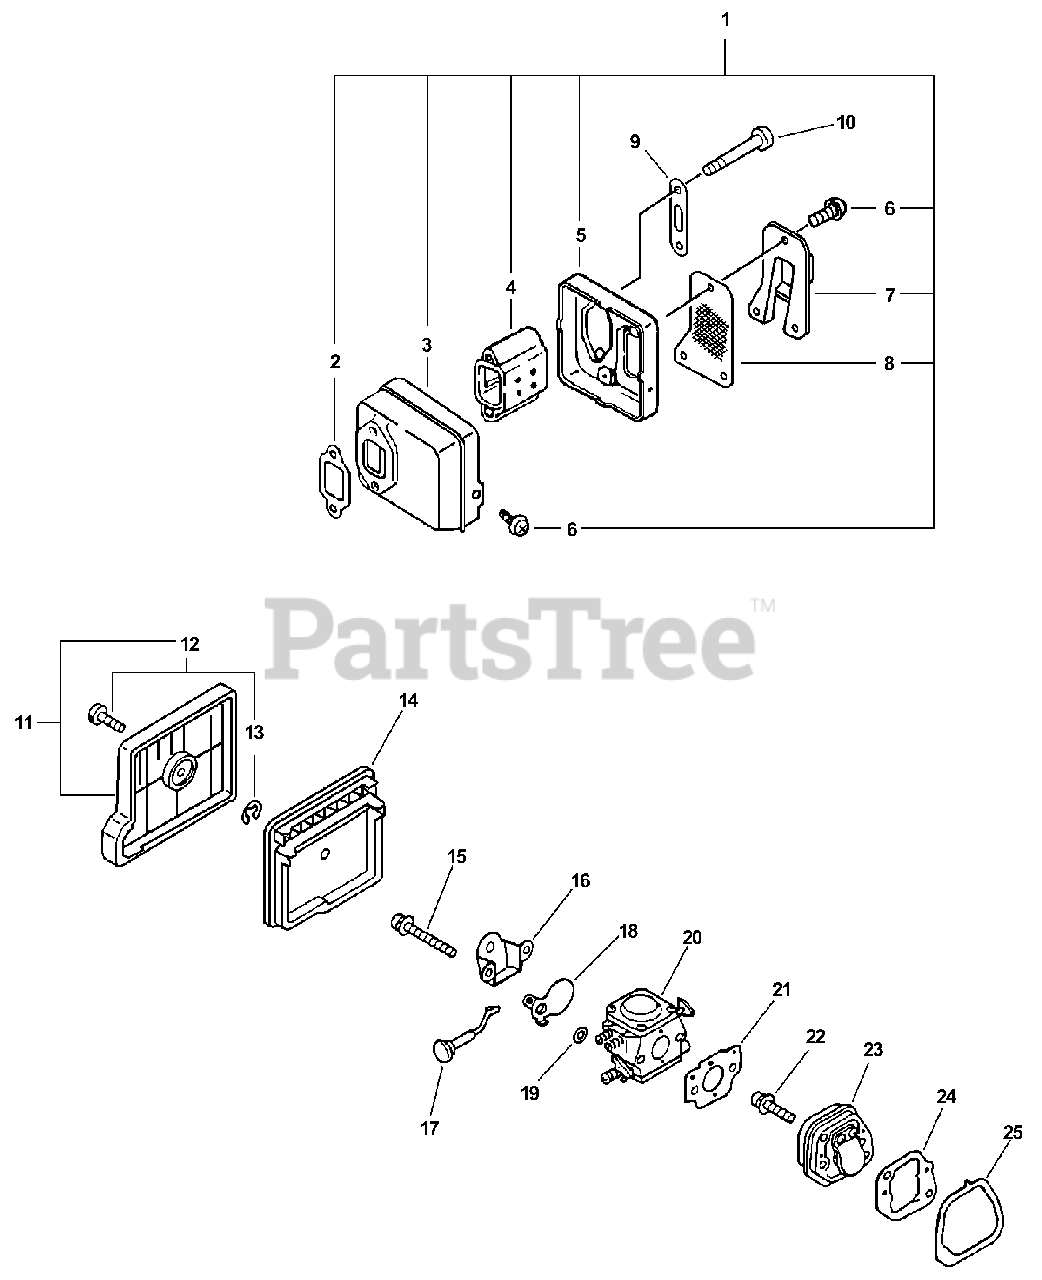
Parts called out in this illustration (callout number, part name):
1	MUFFLER ASSY
2	GASKET, EXHAUST
3	GUIDE, EXHAUST
4	BAFFLE, MUFFLER
5	GUIDE, EXHAUST
6	SCREW - 4X8
7	GUIDE, EXHAUST
8	SCREEN, SPARK ARRESTOR
9	PLATE
10	BOLT - FLANGE
11	AIR FILTER COVER ASSY
12	THUMBSCREW
13	RING, RETAINING - 4
14	FILTER, AIR
15	SCREW - 5X45
16	PLATE, PREVENT
17	ROD, CHOKE
18	SHUTTER, CHOKE
19	WASHER
20	CARBURETOR WT-385A
20	CARBURETOR WT-402A
21	GASKET, INTAKE
22	SCREW - 5X18
23	INSULATOR KIT
24	GASKET, INTAKE
25	SEAL
